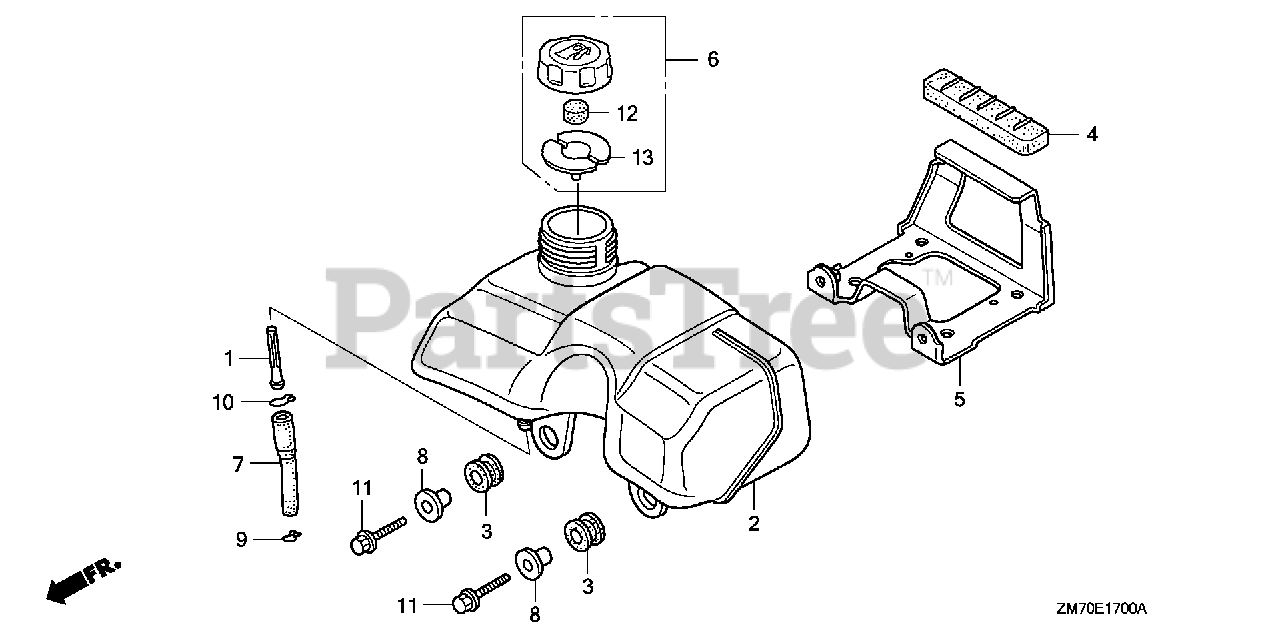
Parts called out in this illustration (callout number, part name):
1	FILTER, FUEL
2	TANK, FUEL
3	RUBBER A, TANK MOUNTING
4	RUBBER B, TANK MOUNTING
5	STAY, FUEL TANK
6	CAP ASSY., FUEL TANK
7	TUBE A, FUEL
8	COLLAR, CANISTER MOUNTING
9	CLIP, TUBE (B8)
10	CLIP, TUBE (B10)
11	BOLT, FLANGE (6X20)
12	SPONGE, FUEL CAP BREATHER
13	GASKET, FUEL CAP
